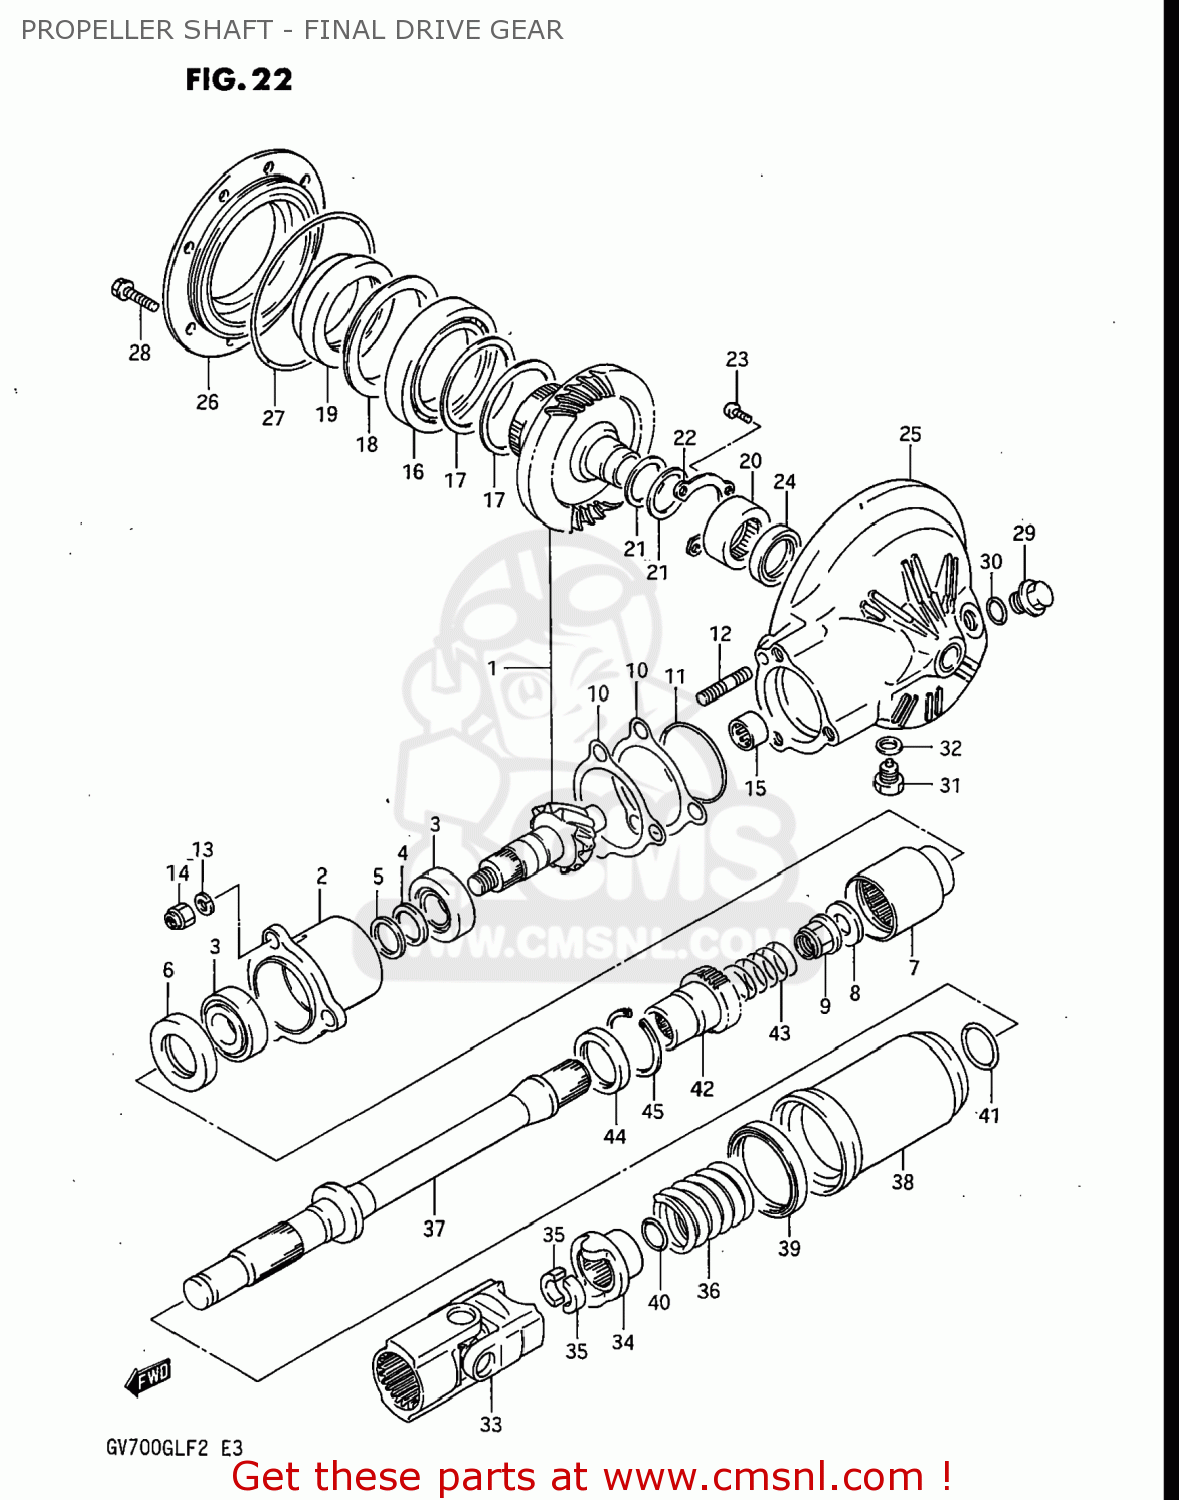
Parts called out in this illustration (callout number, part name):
1	GEAR SET,FINAL BEVEL
2	HOUSING,FINAL BEVEL GEAR
3	BEARING
4	SPACER
5	SHIM (25X30X2
6	SEAL,OIL(32X54X7)
7	GEAR,FINAL DRIVE
8	WASHER(14X29X4)
9	NUT
10	SHIM,DRIVE GEAR HOUSING
11	O RING(D:2.4,ID:62.6)
12	STUD
13	LOCK WASHER
14	NUT
15	BEARING
16	BEARING(70X110X13)
17	SHIM,DRIVEN GEAR BEARING T0.35
18	PLATE,FINAL DRIVEN BRG OIL
19	SEAL,OIL(70X96X16)
20	BEARING(32X46X17.7)
21	SHIM,FINAL DRIVEN GEAR
22	RETAINER,FINAL DRIVEN GEAR BRG
23	SCREW 6X12
24	SEAL,OIL(30X42X7)
25	CASE,FINAL GEAR
26	CASE,FINAL GEAR BEARING
27	O RING(D:3.5,ID:131.6)
28	BOLT
29	PLUG
30	O RING(D:2.4,ID:17.8)
31	PLUG
32	GASKET(14X19.2X2) (NAS)
33	YOKE,UNIVERSAL JOINT
34	DOG,OUTPUT CAM
35	STOPPER,CAM DOG
36	SPRING
37	SHAFT,PROPELLER
38	COVER,PROPELLER SHAFT DA
39	OIL SEAL
40	O RING(D:2.4,ID:15.8)
41	O RING(D:2,ID:23.5)
42	COUPLING,PROPELLER SHAFT
43	SPRING
44	SEAL,OIL(30X40.5X5.5)
45	CIRCLIP
